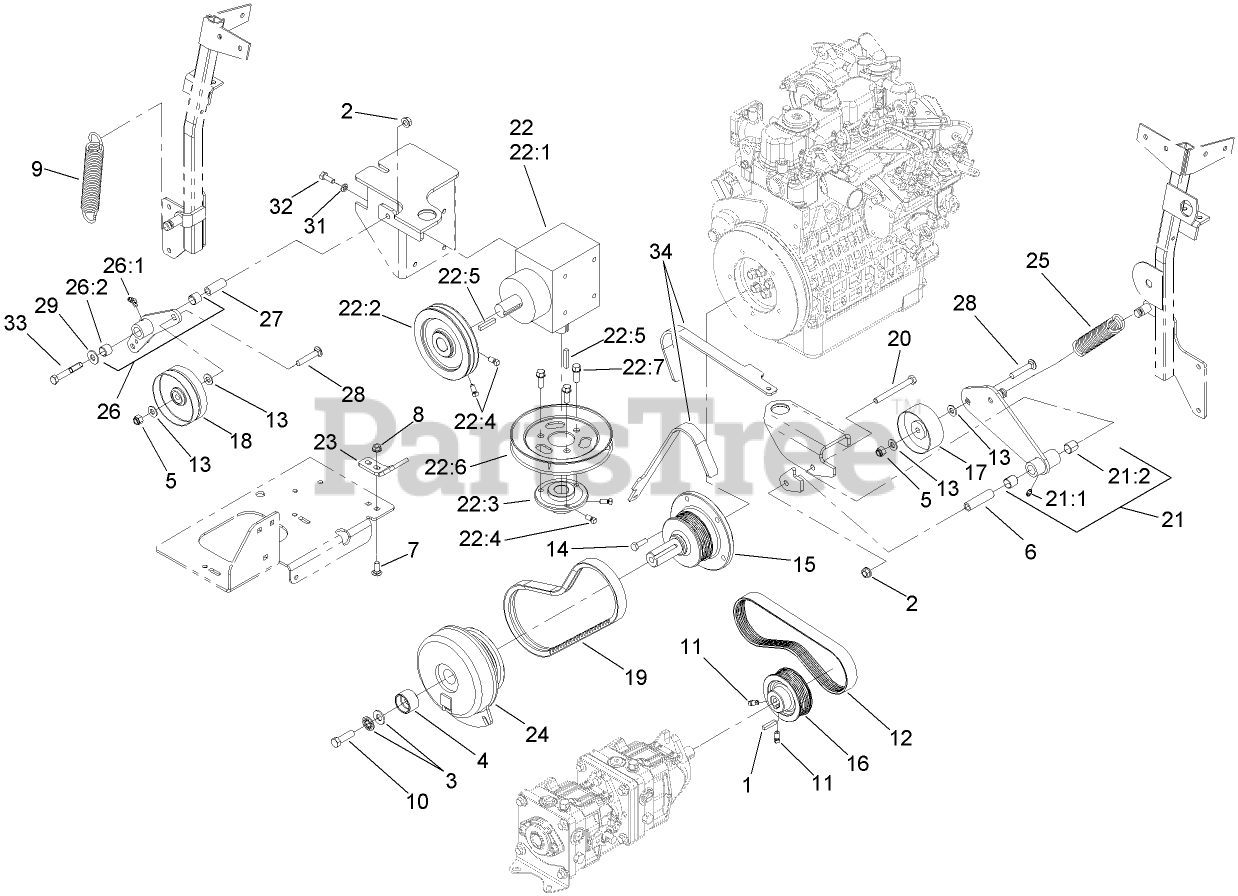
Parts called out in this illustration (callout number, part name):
2	NUT-HHF, WHIZ
3	WASHER-SPRING
4	RETAINER-CLUTCH
5	NUT-LOCK, NI
6	BUSHING-PIVOT, IDLER
7	SCREW-CARR
8	NUT-HF
9	SPRING-EXTENSION
10	SCREW-HH
11	SCREW-SET
12	BELT-V
13	WASHER-FLAT
14	SCREW-HH
15	SHAFT-STUB
16	PULLEY
17	PULLEY-FLAT
18	PULLEY-FLAT
19	BELT-V
20	SCREW-HH
21	PUMP IDLER ARM ASM
21:1	FITTING-GREASE
21:2	SLEEVE-BEARING
22	Gearbox ASM
22:1	GEARBOX-90 DEG
22:2	PULLEY
22:3	HUB-PULLEY
22:4	SCREW-SET
22:5	KEY-SQUARE
22:6	PULLEY-B SECTION
22:7	SCREW-HWH
23	BRACKET-CLUTCH STOP
24	CLUTCH-ELECTROMAGNETIC
25	SPRING-EXTENSION
26	GEARBOX IDLER ASM (W/BEARINGS)
26:1	FITTING-GREASE
26:2	SLEEVE-BEARING
27	BUSHING
28	SCREW-CARR
29	WASHER-FLAT
31	WASHER-LOCK
32	SCREW-HH
33	SCREW-HH
34	TOOL-ALIGNMENT, PULLEY
